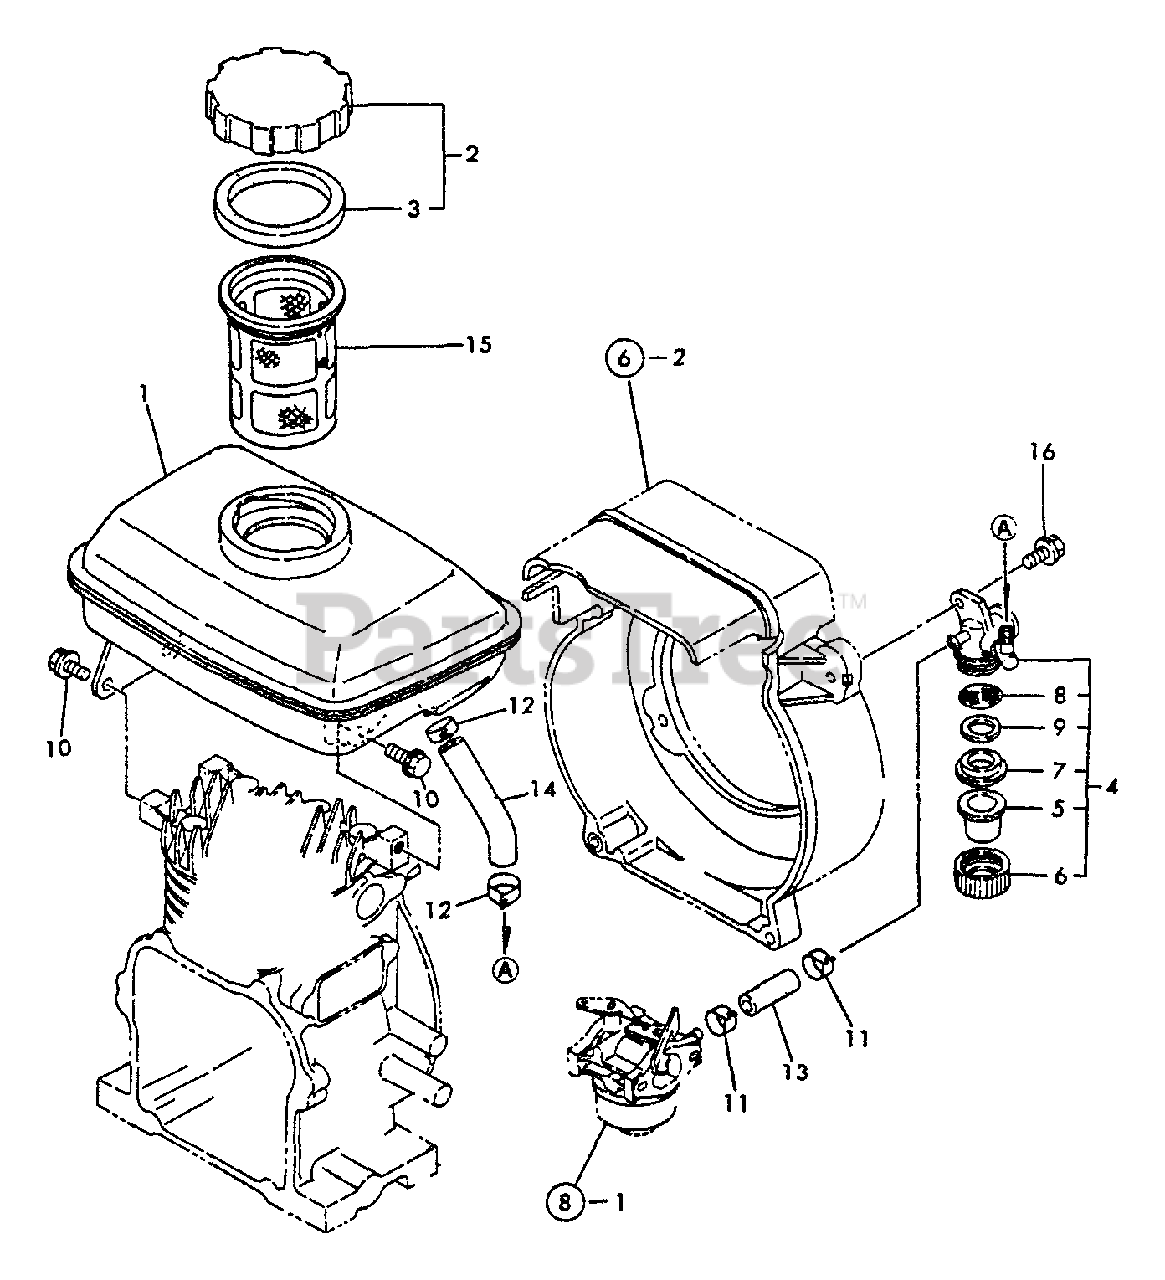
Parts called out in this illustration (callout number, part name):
1	FUEL TANK ASSY
2	CAP ASSY
3	GASKET
4	COCK ASSY, FUEL
5	BOWL, STRAINER
6	RETAINER
7	GASKET
8	FILTER, FUEL
9	PLATE
10	BOLT - 6×8 -- PLATED
11	CLAMP, HOSE - 9
12	CLAMP, HOSE
13	PIPE, FUEL
14	PIPE, FUEL
15	STRAINER, FUEL
16	BOLT - 6×12 -- PLATED
